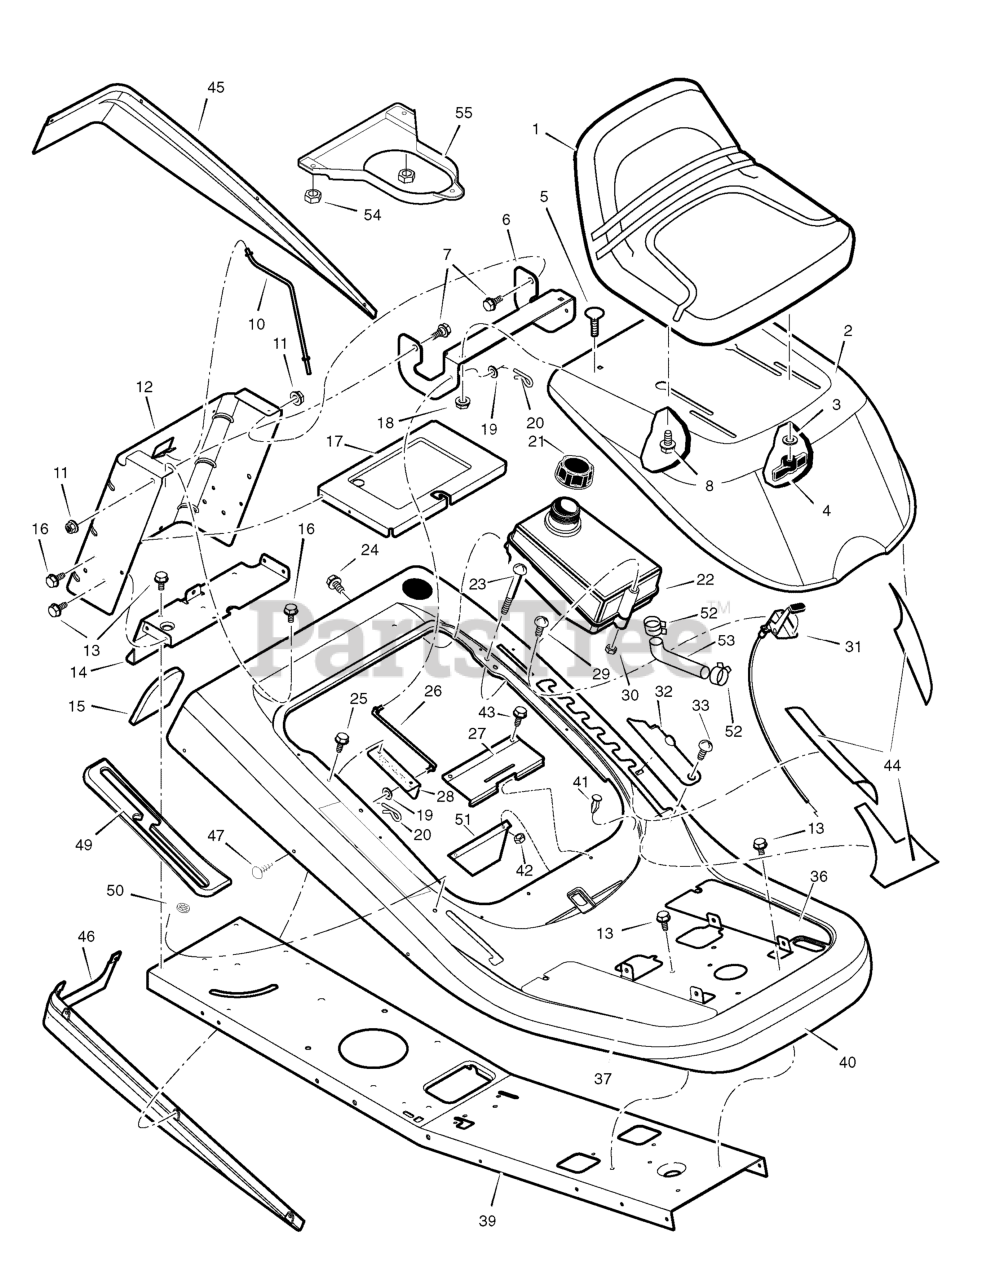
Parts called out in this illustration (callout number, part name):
1	Seat
3	Washer
4	Bolt, Wing
5	Bolt, Carriage
6	Bracket, Hinge
7	Bolt, Shoulder
8	Bolt, Shoulder
10	Rod, Battery
11	Nut, Flange
12	Plate, Rear
14	Plate, Hitch
17	TRAY, Battery
18	Nut, Flange
20	Pin, Hair
21	Cap, Fuel Tank
22	Tank, Fuel
23	Screw
26	Rod, Hood Prop
27	Spring, Seat Deck
28	Bracket, Prop Rod
30	Nut, NY-Lock
31	Control, Throttle
32	Cover, Detent (Black)
33	Bolt, Shoulder
36	Footmat, Left (Black)
37	Footmat, Right (Black)
40	Deck, Seat
42	Nut
43	Screw
44	Kit, Foil Heat Shield
45	Trim, Left
46	Trim, Right
47	Fastener, Panel
49	Cover, Long Black
50	Nut, Push
51	Heat Shield
52	Clamp, Hose
53	Line, Fuel
54	Nut, Hex 5/16-18
55	Plenum, Engine
